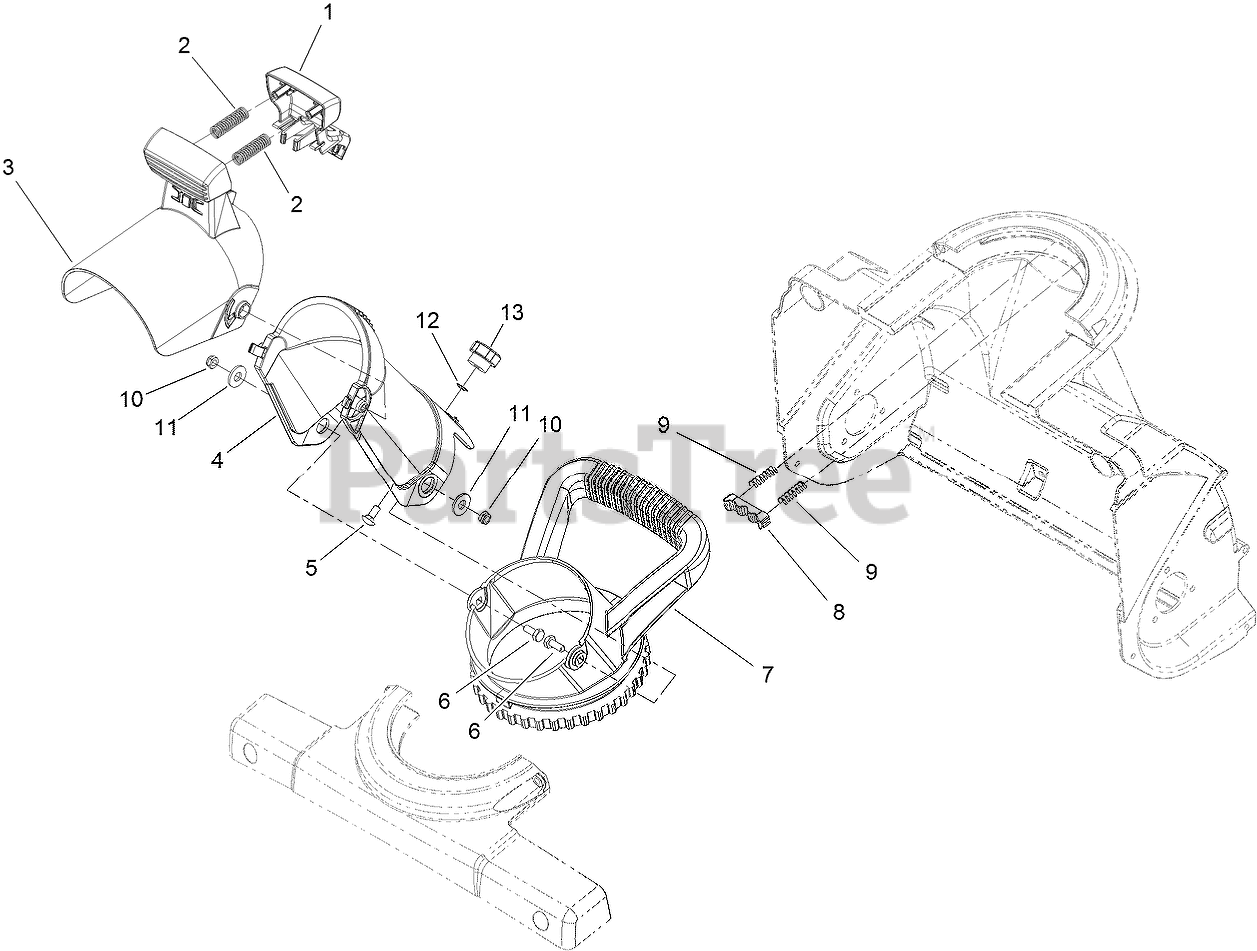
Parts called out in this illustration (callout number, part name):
1	TRIGGER-DEFLECTOR
2	SPRING-COMPRESSION
3	CHUTE DEFLECTOR ASM
4	CHUTE-DISCHARGE
5	BOLT-CARR
6	SCREW-HH
7	HANDLE-CHUTE
8	DETENT-CHUTE
9	SPRING-COMPRESSION
10	NUT-HEX
11	WASHER-PLAIN
12	PUSHNUT-RETAINER, BOLT
13	KNOB-CHUTE
